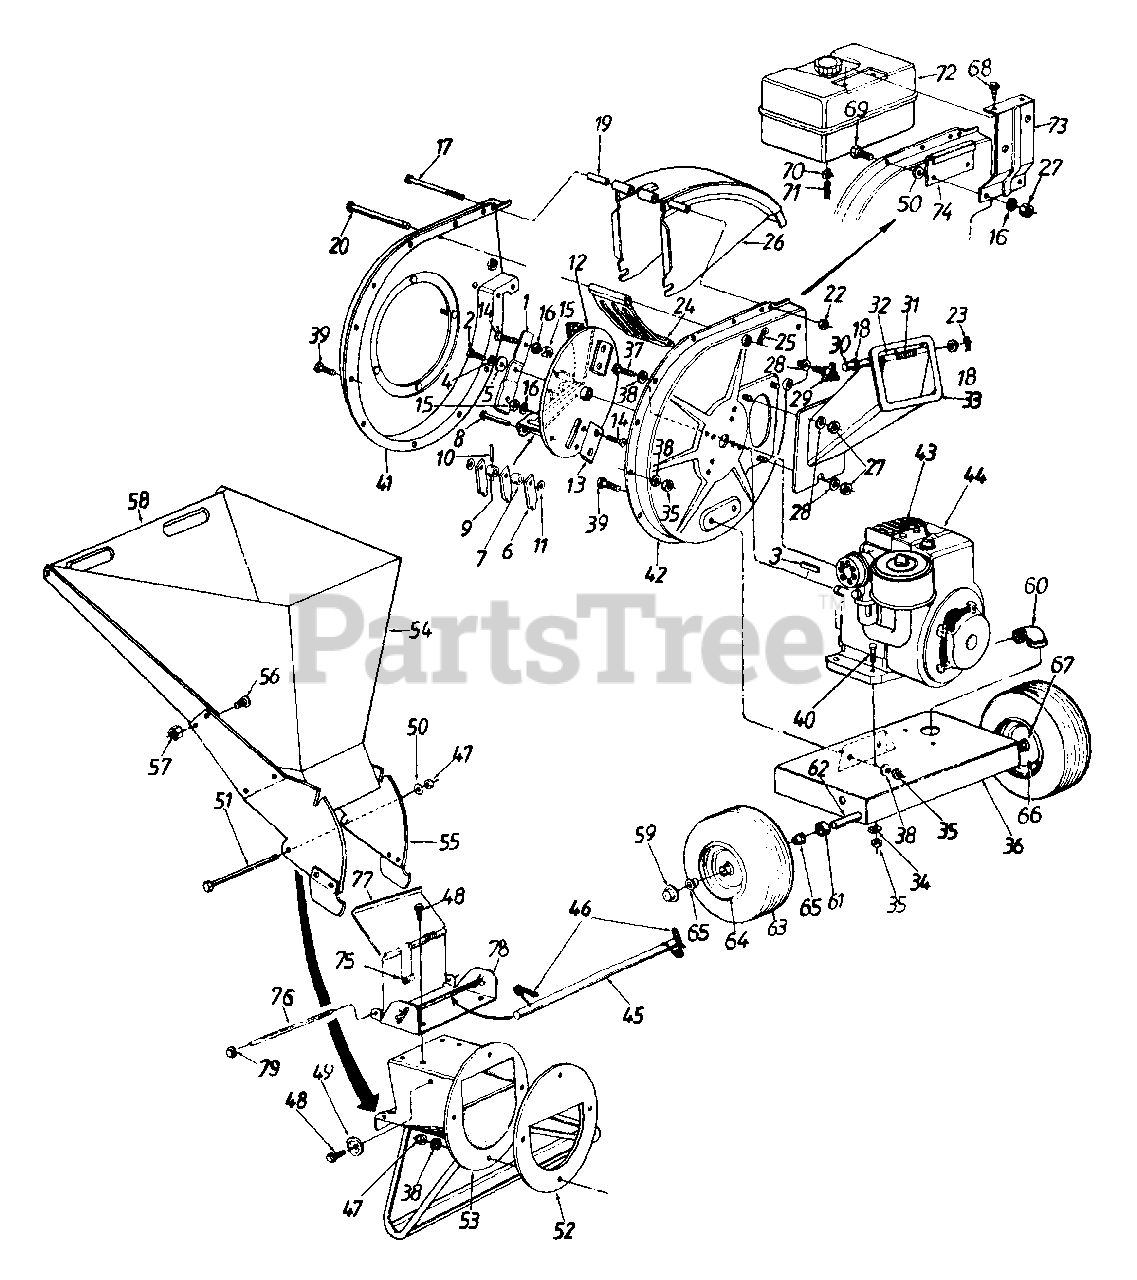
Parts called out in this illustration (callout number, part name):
1	Blade
2	Hex Patch Bolt 3/8-24 x 2" Lg. (Gr. 8)
3	Sq. Key 1/4 x 2.0" Lg.
4	L-Wash. 3/8" I.D. H.D.
5	Fl-Wash..406" I.D. x 1.25" O.D. Hdn.
6	Flail
7	Flail Spacer
8	Clevis Pin .496" Dia.
9	Flail Spacer w/.160" Dia. Hole
10	Spring Roll Pin 1.12" Lg.
11	Fl-Wash..531" I.D. x.94" O.D.
12	impeller Ass'y. Comp.
13	Chipper Blade
14	Flat Hd. Scr. 5/16-24 x .75" Lg.
15	Hex Top L-Nut 5/16-24 (Gr. 5)
16	L-Wash. 5/16" I.D.
17	Hex Bolt 1/4-20 x 3.75" Lg.
18	Fl-Wash..281" I.D. x .5" O.D.
19	Chute Hinge Spacer 1.66" Lg.
20	Clevis Pin .5" Dia. x 4.62" Lg.
22	Hex Ctr. L-Nut 1/4-20 Thd.
23	Cotter Pin 3/32" x 5/8"
25	Internal Cotter Pin 3/8" Dia.
27	Hex Nut 5/16-18 Thd. (Gr. 5)
28	Bell-Wash..345" I.D. x .88"
29	Hand Knob
30	Chipper Door Rod
31	Torsion Spring 1.14" Lg.
35	Hex Nut 5/16-18 Thd. (Gr. 5)
38	L-Wash. 5/16" I.D.
39	Hex Bolt 5/16-18 x .75" Lg. (Gr. 5)
40	Hex Bolt 5/16-18 x 1.75" Lg.
44	Engine
45	Release Bar
46	Torsion Spring 1.06" Lg.
47	Elastic Lock Nut 5/16-18 Thd.
48	Hex Wash. Hd. Self-Tap Scr. 5/16-18 x .75" Lg.
49	Stop Washer
50	Fl-Wash. 5/16" I.D.
51	Hex Bolt 5/16-18 x 8.38" Lg.
57	Hex L-Nut 1/4-20 Thd.
60	Drain Elbow (5 HP B & S)
61	Spacer .64" I.D. x .38" Lg.
62	Shredder Axle
64	Rim Only
65	Flange Bearing .632" I.D.
66	Air Valve
67	Grease Fltting
68	Hex Hi-Low Scr. 1/4 x .75"
69	Hex Bolt 5/16-18 x .88" Lg.
70	Hose Clamp
71	Fuel Line - 7 in.
72	Fuel Tank Ass'y. Comp.
76	Hopper Door Rod
